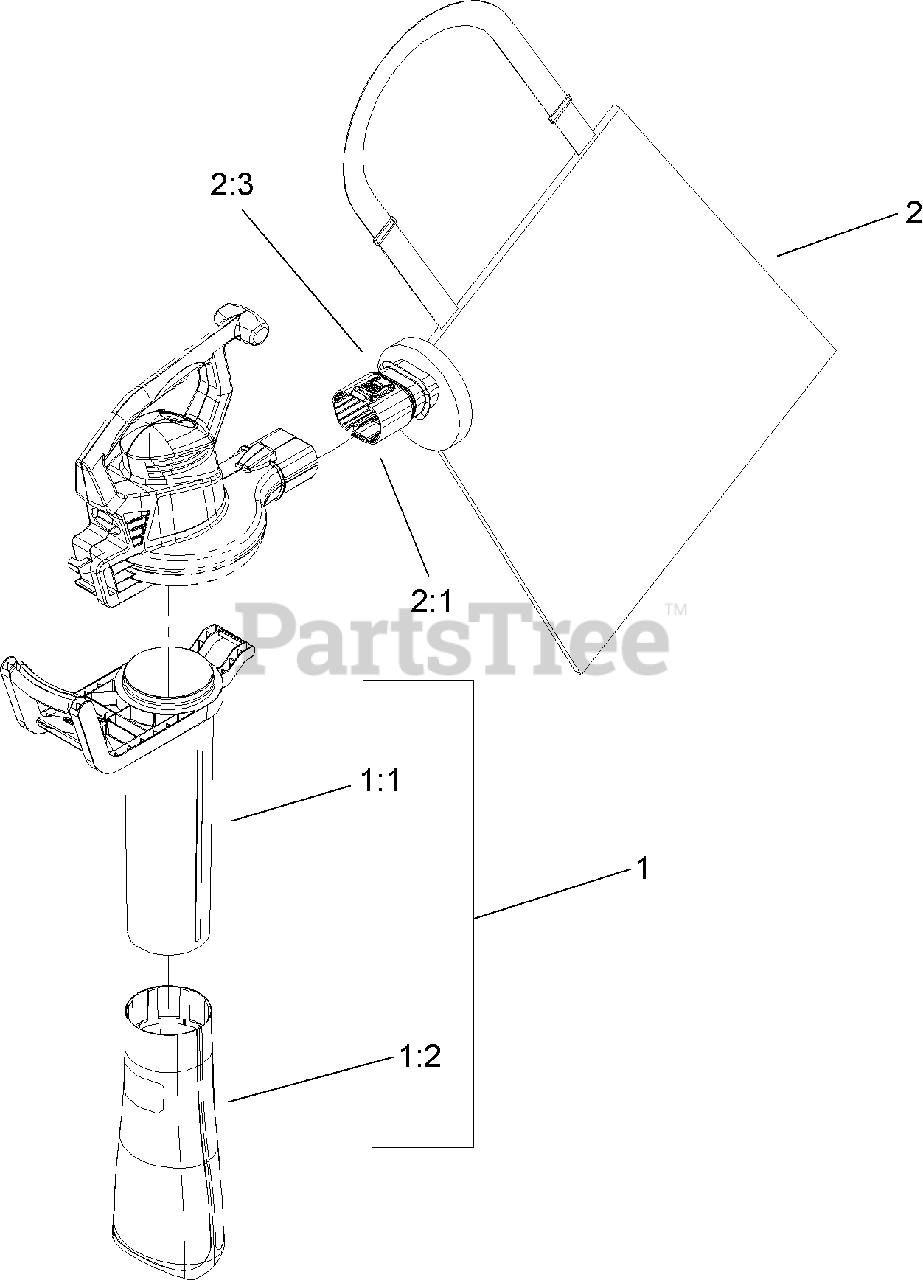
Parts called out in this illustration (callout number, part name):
1	Vac Tube ASM
1:1	TUBE-VAC, UPPER
1:2	TUBE-VAC, LOWER
2	BAG ASM
2:1	COLLAR-BAG
2:3	TIE-CABLE
